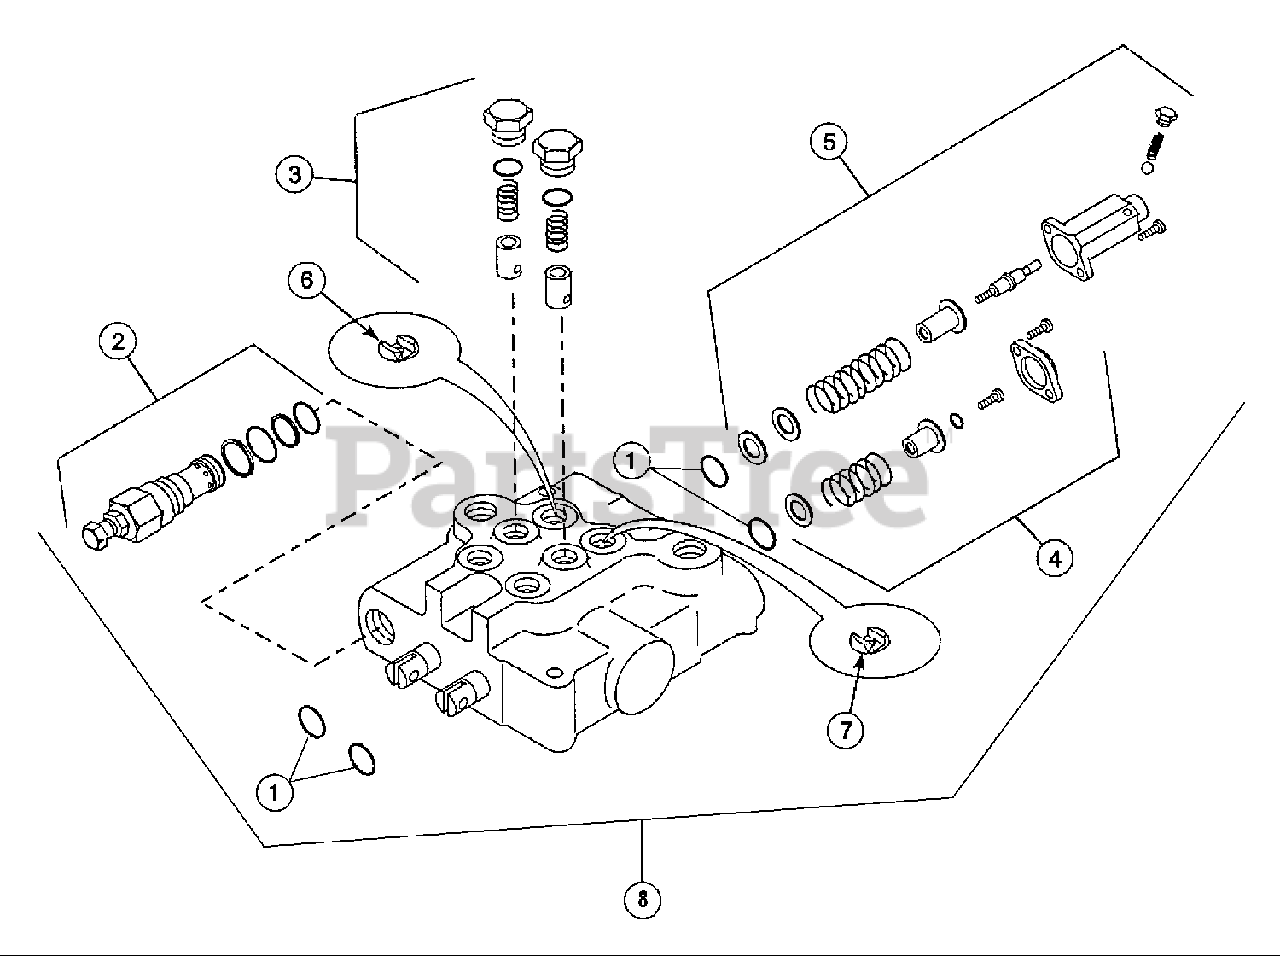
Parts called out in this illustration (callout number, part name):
1	KIT, Seal Repair
2	KIT, Pilot Relief Valve
3	KIT, Load Check
4	KIT, Spring Centering
5	KIT, Detent Spring Centering
6	RESTRICTOR PLATE, One-Way, .109
7	RESTRICTOR PLATE, Two-Way, .062
8	HYDRAULIC VALVE ASSEMBLY
